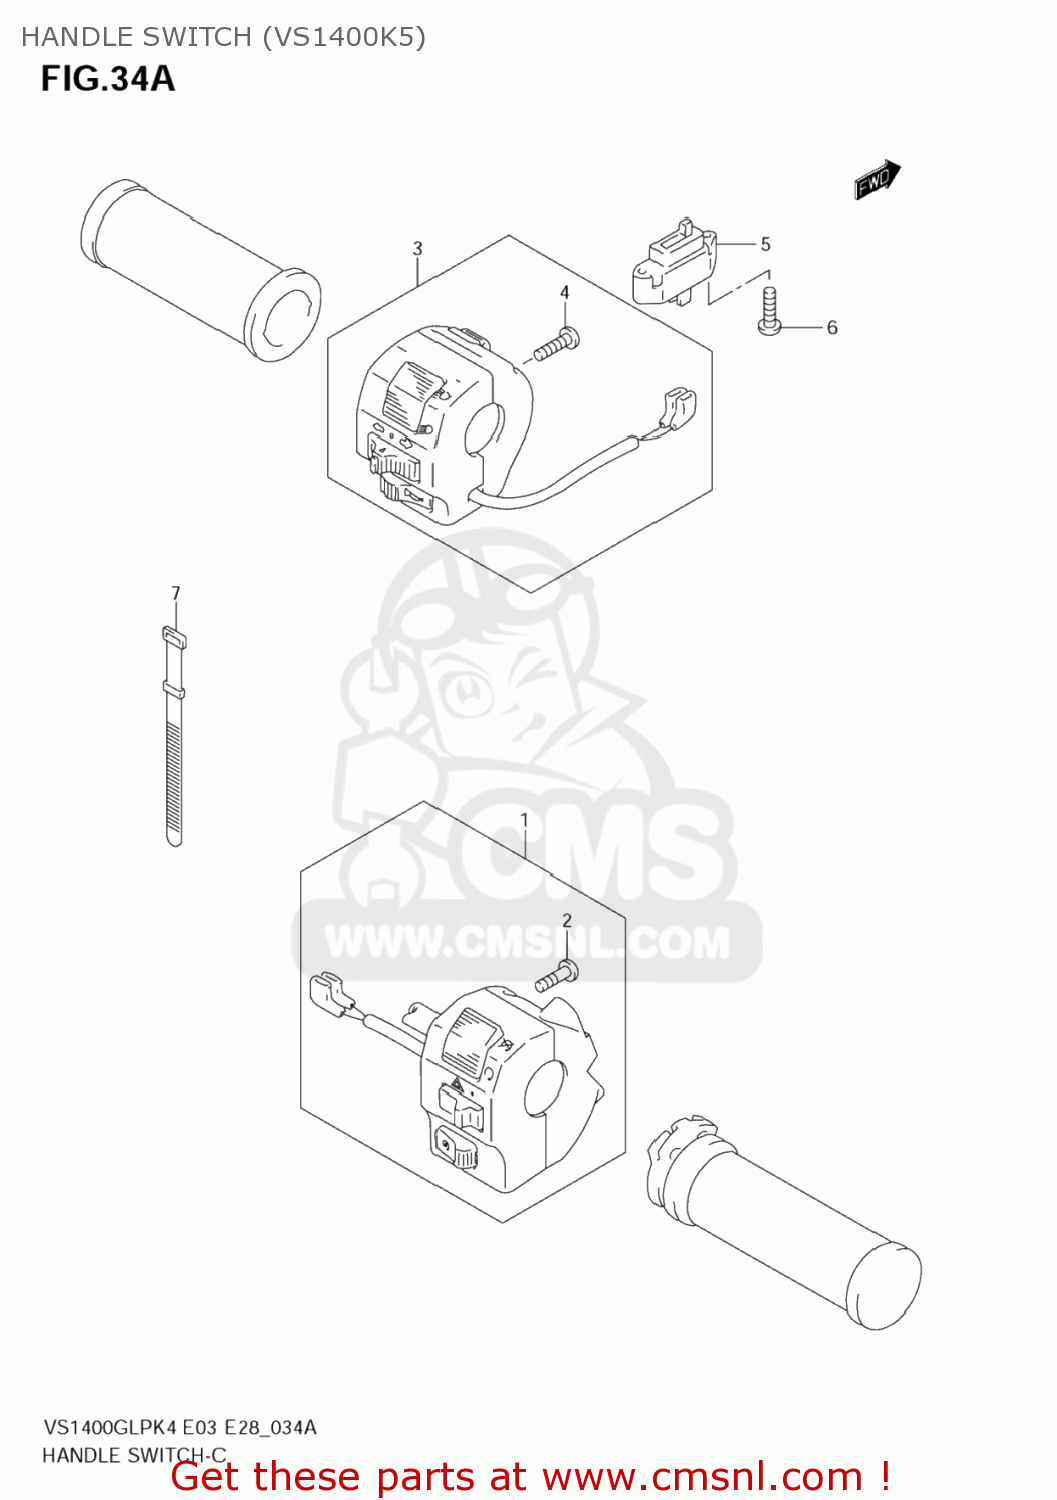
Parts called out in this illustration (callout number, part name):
1	SWITCH ASSY,HANDLE,R
2	SCREW
3	SWITCH ASSY,HANDLE,L
4	SCREW
5	SWITCH ASSY,CLUTCH
6	SCREW
7	CLAMP
